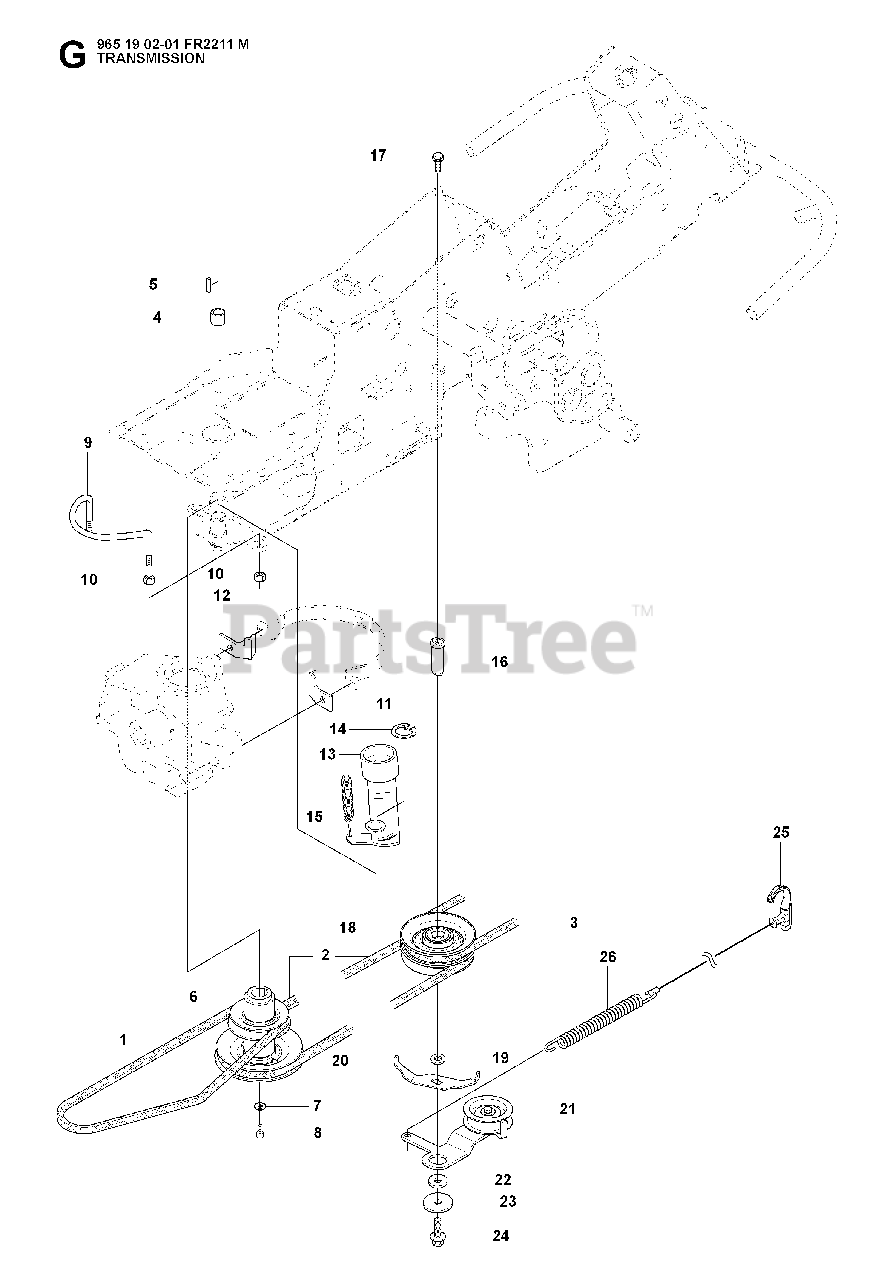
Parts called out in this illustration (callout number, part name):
1	TRANSMISSION BELT
2	BELT
6	PULLEY CPL
9	BELT GUIDE
11	BELT GUIDE CPL., RIGHT
12	BELT GUIDE CPL.,LEFT
13	TENSIONER
14	RETAINING RING SGA 25
16	SHAFT
20	BELT GUIDE
24	BOLT
